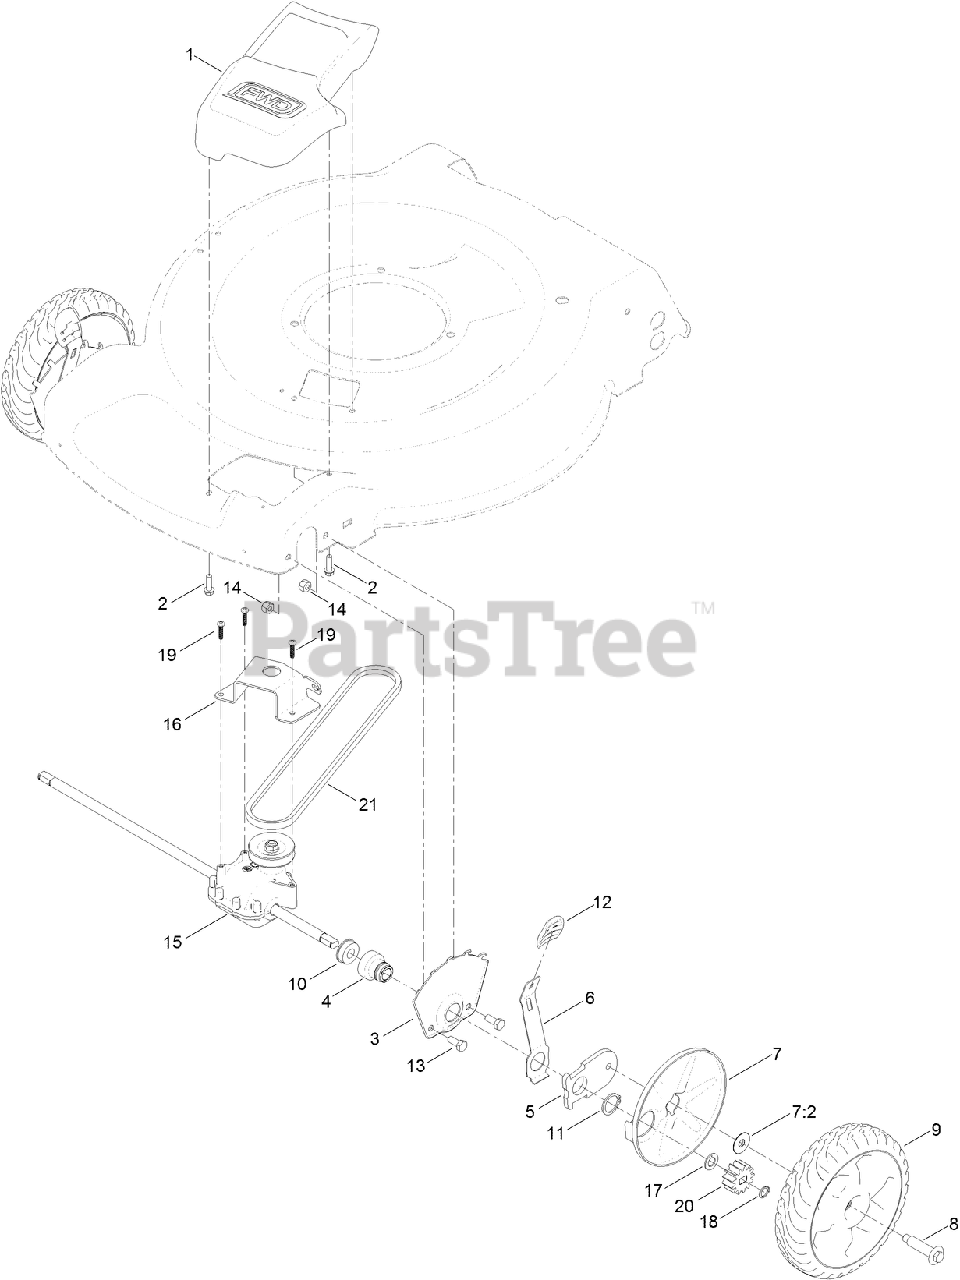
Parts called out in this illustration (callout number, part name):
2	SCREW-HWH
3	PLATE-HOC, FRONT
4	RETAINER-BEARING, HOC
6	ARM-SPRING
7	WHEEL COVER ASM
7:2	WASHER-STEPPED
8	BOLT-SHOULDER
10	BEARING-BALL
11	RING-RETAINING
12	KNOB-LEVER, HOC
13	SCREW-HH
14	NUT-LOCK, NI
16	BRACKET-TRANSMISSION
17	WASHER-THRUST
18	RING-RETAINING
19	SCREW-PLASTITE
20	GEAR-PINION, 13T
21	V-BELT
